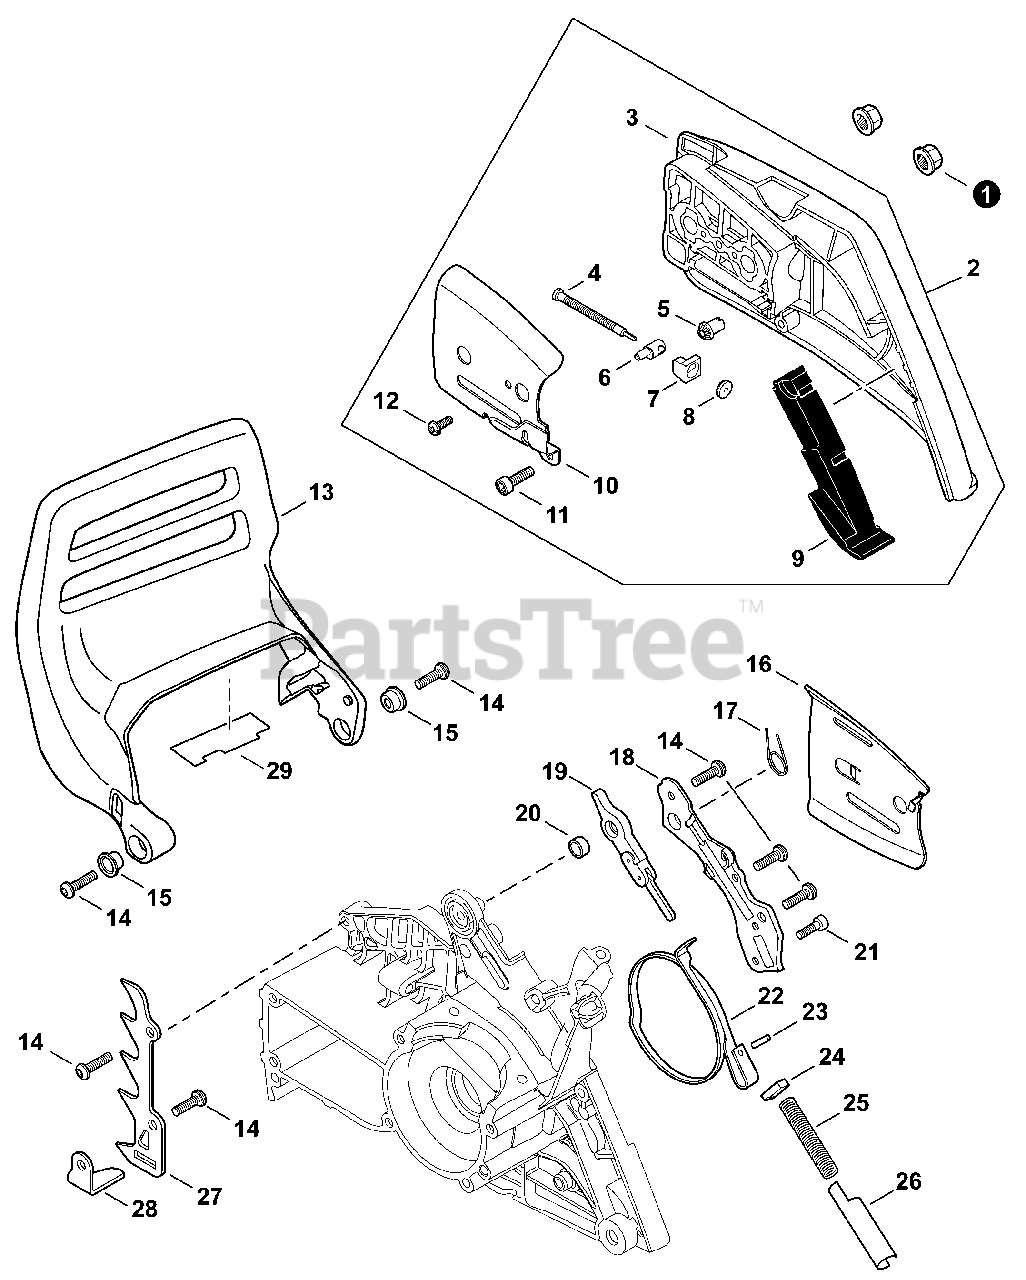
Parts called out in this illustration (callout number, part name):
1	NUT, FLANGE M8×1.25
2	GUARD KIT, SPROCKET
3	GUARD, SPROCKET
4	SCREW, CHAIN TENSION 63 MM
5	GEAR, BEVEL
6	TENSIONER, CHAIN
7	COLLAR 8
8	GEAR, BEVEL
9	CUSHION
10	PLATE, GUIDE - OUTER
11	BOLT, TORX 4×12
12	SCREW 3×6
13	LEVER, BRAKE
14	BOLT, TORX 5×16
15	COLLAR 11.2×16.2×T0.6
16	PLATE, GUIDE - INNER
17	SPRING, TORSION
18	COVER, BRAKE
19	CONNECTOR, BRAKE
20	SPACER 12×10×T: 1.0
21	BOLT, TORX 4×12
22	BAND, BRAKE
23	PIN, SPRING 3x-9.8
25	SPRING, COMPRESSION Ø12×70.5
26	PLATE, SIDE
27	SPIKE, BUMPER
28	CHAIN CATCHER
29	SHIELD, HEAT 75×27×0.15
